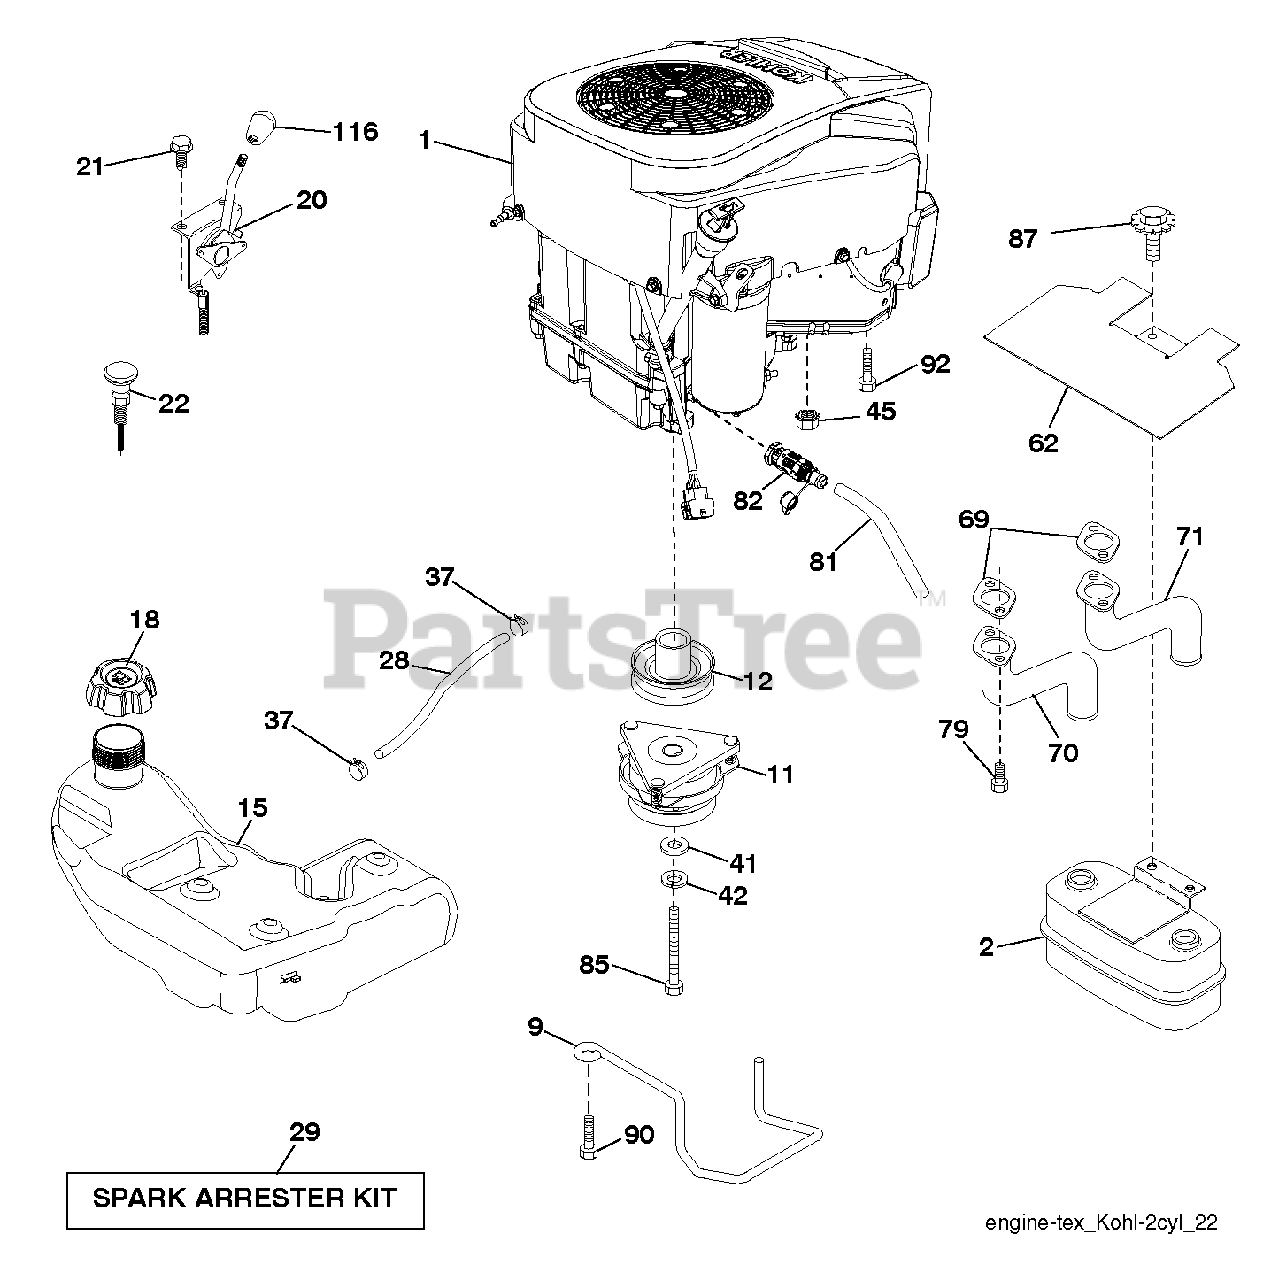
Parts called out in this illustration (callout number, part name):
2	MUFFLER.TWIN.CYL.LOW.TONE
9	KEEPER BELT ENGINE
11	CLUTCH ELECTRIC
12	PULLEY ENGINE
15	TANK.ASM.4.GAL.EPA
18	Fuel Cap, 2-Way Vent
20	CONTROL.THROTTLE.PRO.KOHLER
21	SCREW.#10 X 0.750.BOS THREAD
22	CONTROL CHOKE
28	LINE.FUEL.64"REAR.EMIS
29	ARRESTER SPARK (OPTIONAL)
37	HOSE CLAMP
42	LOCKWASHER
45	NUT
62	SHIELD.HEAT.MUFFLER
69	GASKET.EXHAUST.KOHL.CV18-CV26
70	Exhaust Pipe, LH CV18/20
71	Exhaust Pipe, RH CV18/20
79	SCREW.SOCKET HD.5/16-1
81	TUBE, DRAIN OIL ASM.
82	VALUE.OIL.DRAIN
85	BOLT HEX 7/16-20 X 3.75 GR. 5
87	BOLT 5/1618UNC X 3/4 W/ SEMS
90	SCREW 3/8-16X1
92	SCREW 3/8-16X1
116	KNOB - SHIFT
